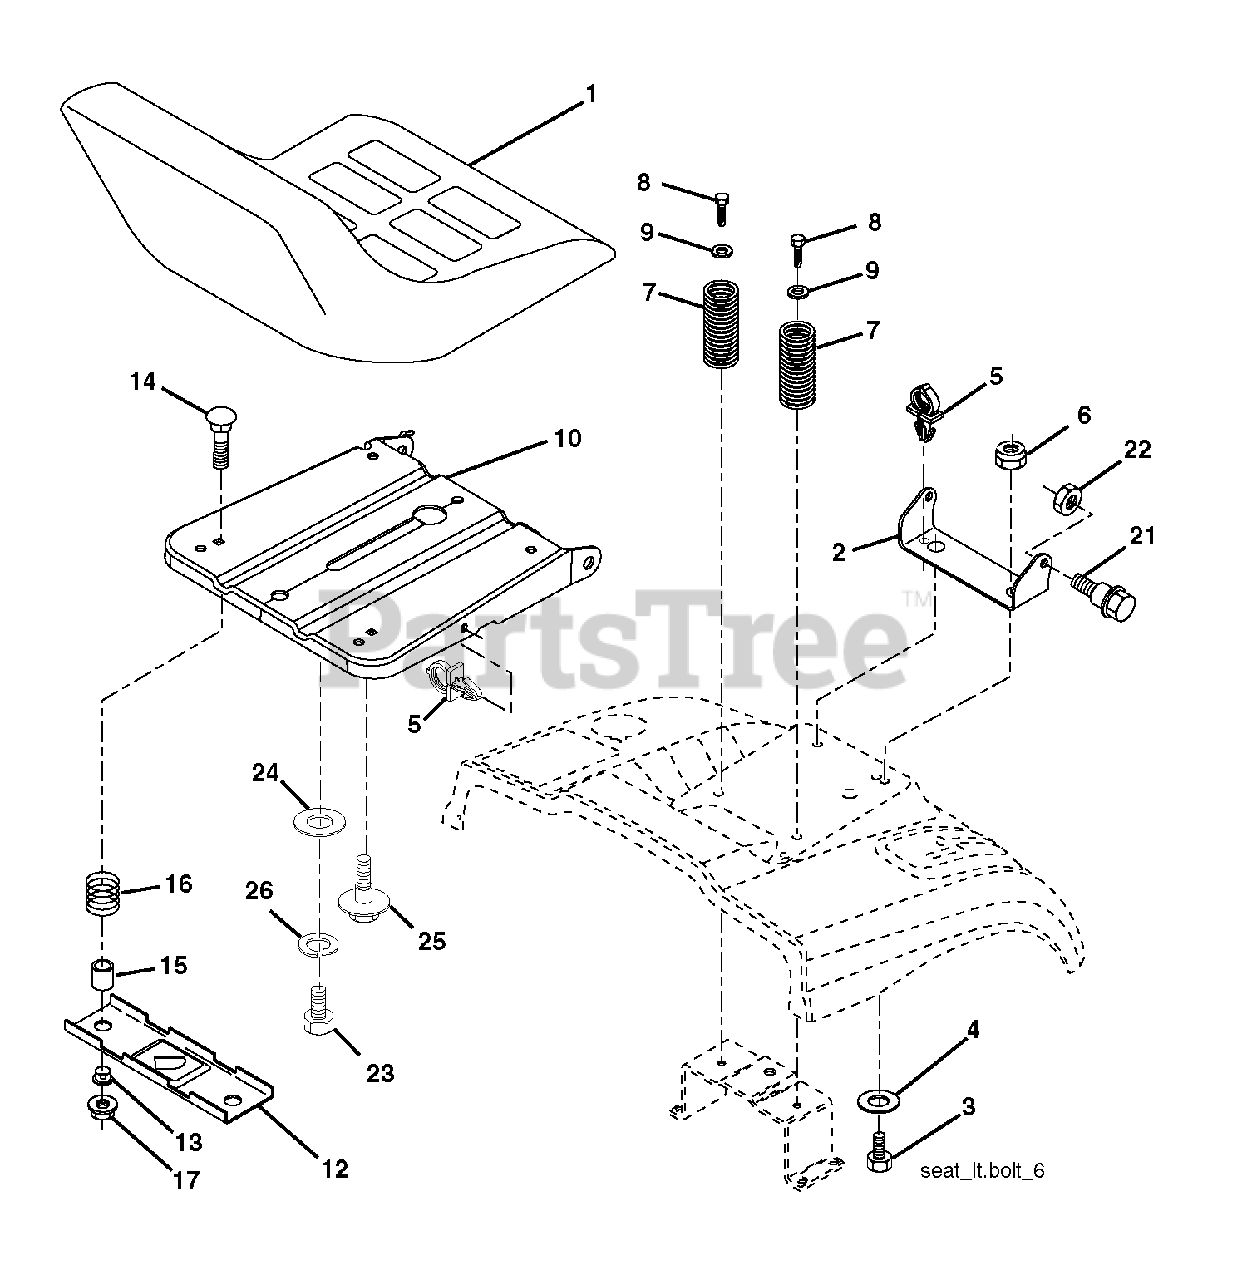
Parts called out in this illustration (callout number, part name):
1	SEAT.XG090.BLK.KB/BLT.NO-LOG
2	SEAT PIVOT BRKT
4	WASHER PM
5	PUSH CLIP
6	NUT
7	SPRING COMPRESSION
8	SCREW 3/8-16X1
9	WASHER
10	PAN.ASM.SEAT.1SLOT
12	BRKT.MNTNG.SWITCH.SEAT
14	BOLT.ROUND.HEAD.SQUARE.NECK
15	SPACER SPLIT 28X.96
17	NUT T
21	BOLT.SHOULDER.5/16-18
22	NUT.71038.31-18.HEX.NYLOCK
23	BOLT.HEX.BLACK
25	BOLT,SHOULD
26	LOCKWASHER
